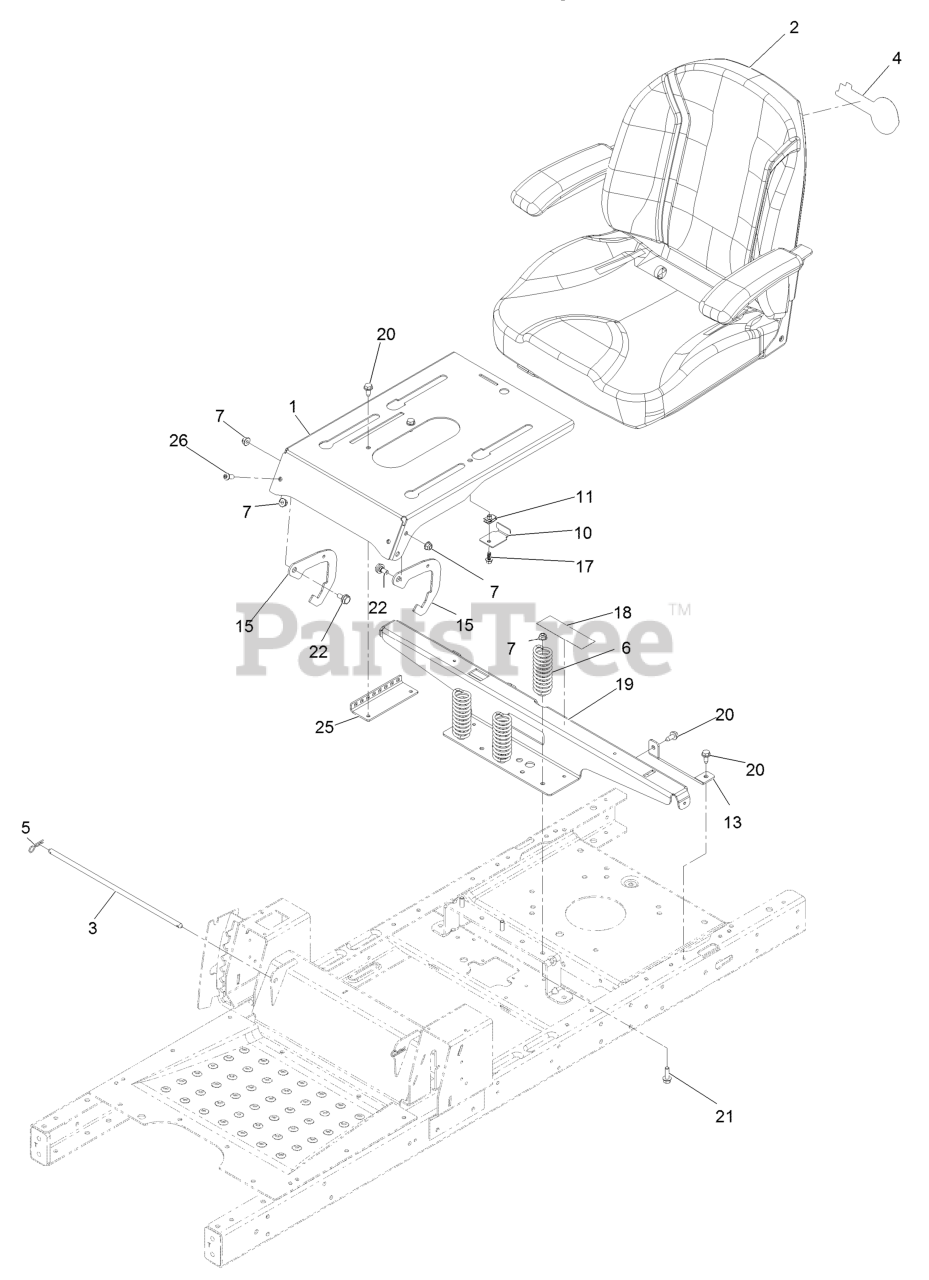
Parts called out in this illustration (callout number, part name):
2	SEAT ASM, EXMARK
3	ROD-PIVOT, NARROW
4	DECAL-EXMARK LOGO
5	PIN-COTTER
6	SPRING-COMPRESSION
7	NUT-HF, NI
10	BRACKET-STOP, SEAT
11	Nut-Retainer-Panel 1/4-20
13	SUPPORT-TANK, REAR
15	LATCH-SEAT
17	SCREW-HHF
18	DECAL-SERVICE, CE
19	SUPPORT-POD
20	Screw-HWH 5/16-18 X 3/4 Tf
21	SCREW-HHF
22	BOLT-SHOULDER,HFH
25	BRACKET-LATCH, SEAT
26	SCREW-HSBH
